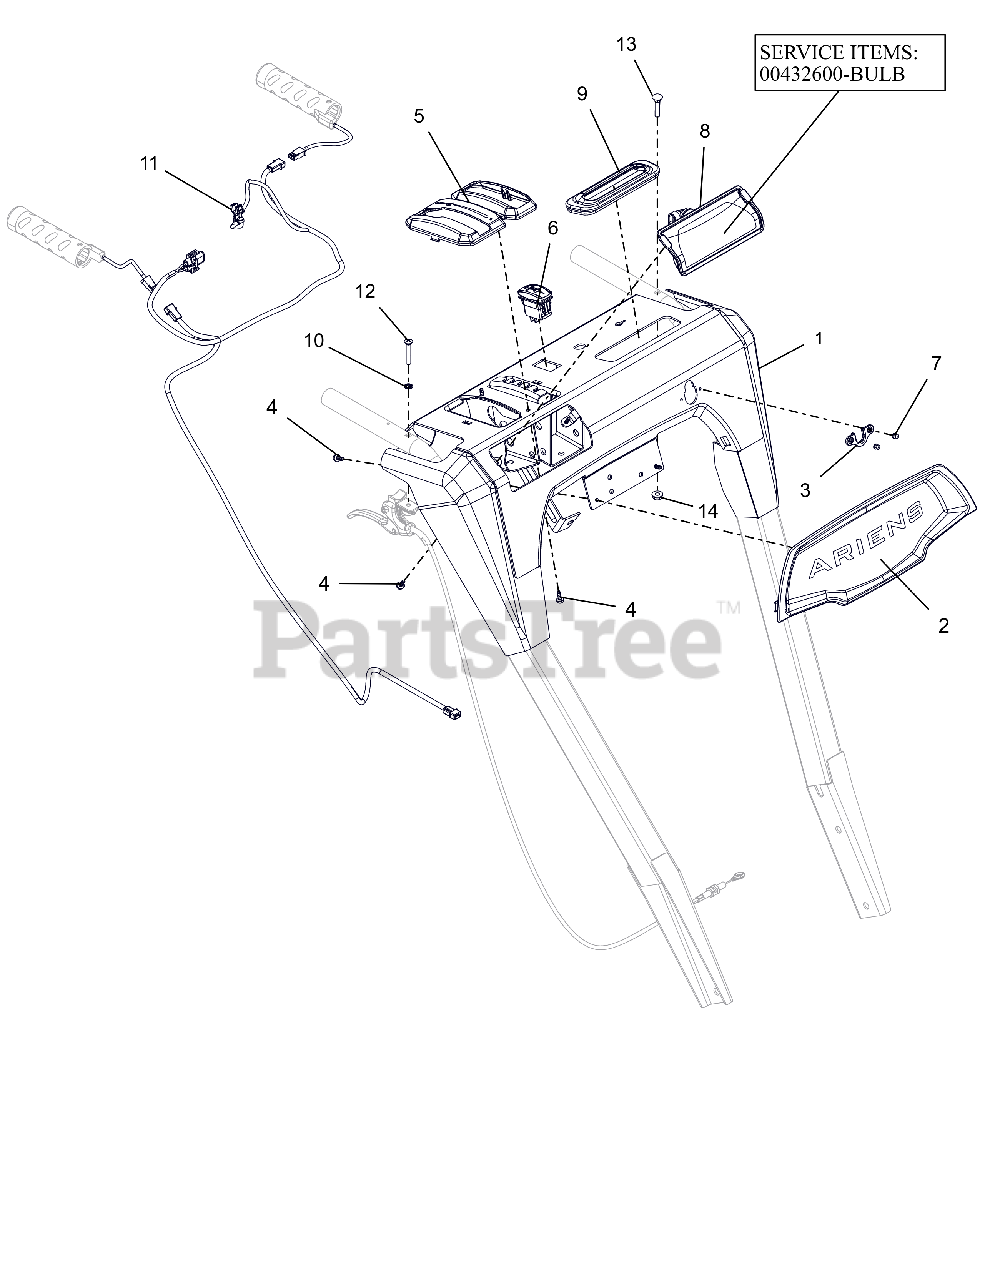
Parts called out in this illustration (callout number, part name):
1	PANEL, DASH-HYDROTRACK W/DECAL
2	BEZEL, DASH - ARIENS LG DASH
3	GROMMET, CABLE, QUICK TURN 2
4	SCR, PLASTIC #10X.50
5	BEZEL, SHIFT - HYDRO SNOW
6	SWITCH,ROCKER SPST-ON/OFF
7	RVT-POP #43 .125X.313 STL ZINC
8	HEADLIGHT ASY, HALO 20W 2SHOT
8	BULB, LIGHT-HALOGEN 20W
9	GROMMET, BOOT, QUICK TURN
10	WSHR-LK-INT .250 TH TYA
11	HARNESS, LIGHT & WARMER
12	SCR,OVAL .25-20X1.50 ZCC
13	BLT-RDHDXLSQNK.25-20X1.25 G5ZC
14	NUT-LK-CTR-FLG .25-20 ZC120
